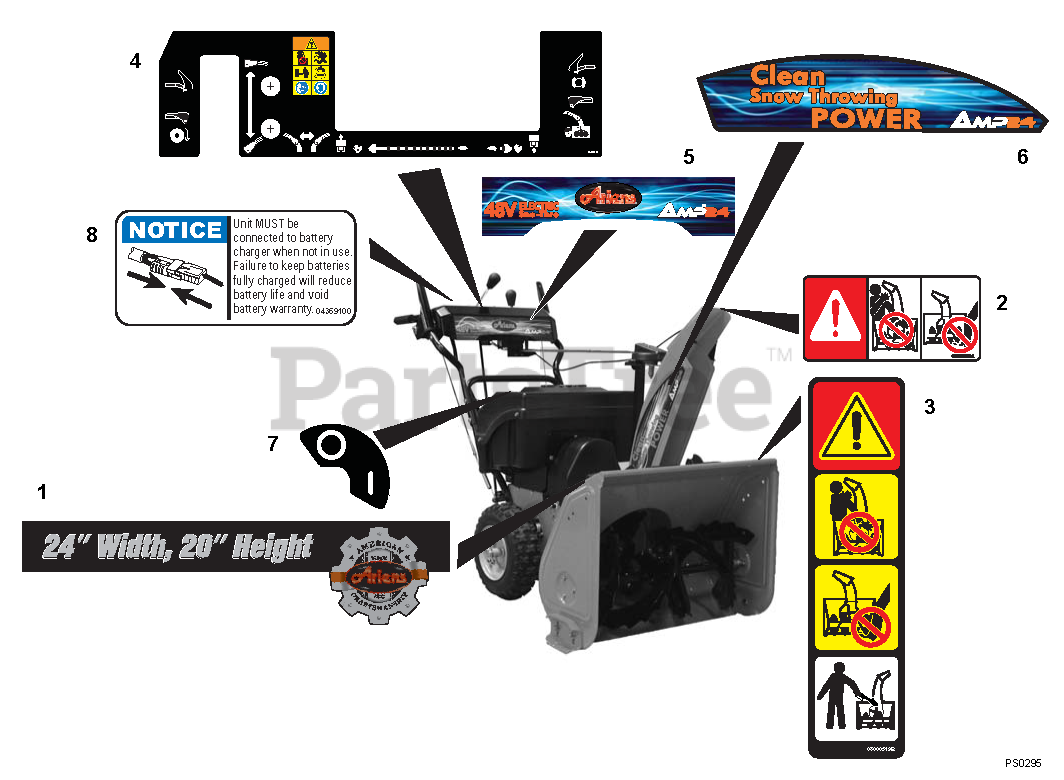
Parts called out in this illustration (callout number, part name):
2	DECAL, DANGER
3	DECAL, DANGER - ROTATING PARTS
4	DECAL,CONTROL - COMPACT REMOTE
5	DECAL, AMP DASH PANEL
6	DECAL, AMP 24 (SNO CHUTE)
7	DECAL, ON/OFF
8	DECAL, CHARGE PORT
